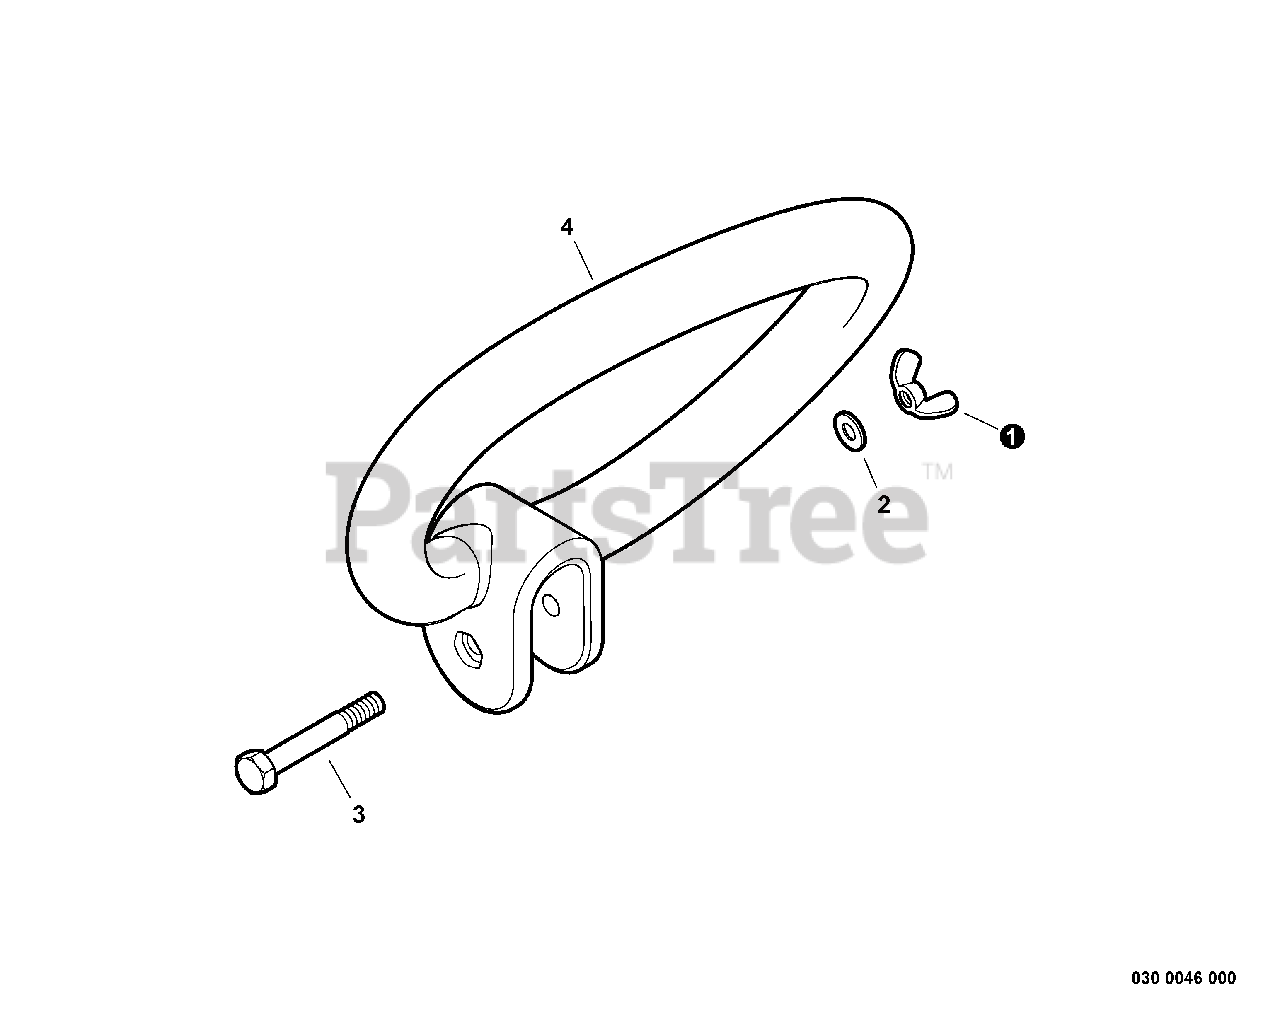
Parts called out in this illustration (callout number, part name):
1	NUT, WING 1/4"-20
2	WASHER, 1/4"
3	BOLT 1/4"-20×2"
4	HANDLE, SUPPORT
